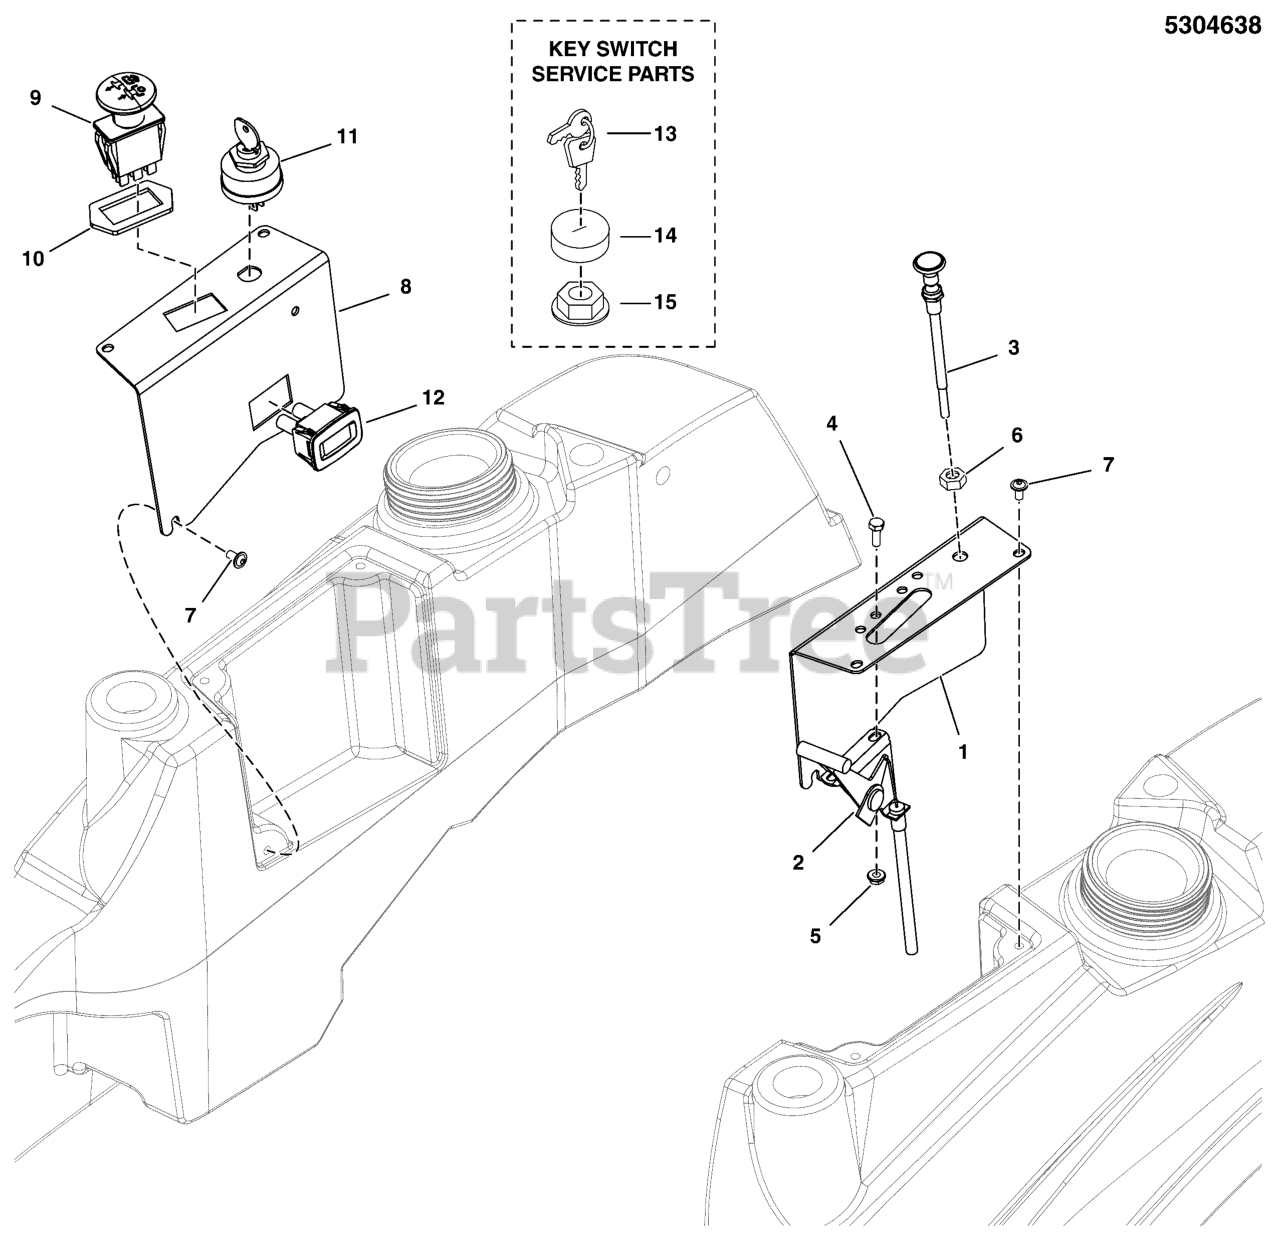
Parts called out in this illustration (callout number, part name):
1	PLATE, CONTROL PANEL, LH, F60Z - BLK
2	CABLE, THROTTLE CONTROL, 51"
3	CABLE, CHOKE CONTROL, 51" (Z)
4	HHCS, 1/4-20 X 0.625, GR5, ZINC/CLEAR
5	NUT, 1/4-20 Hex Nylock Flange
6	NUT, 3/8-24 Hex Jam
7	SCREW, ALLEN HEAD 1/4-20X.500 ZINC PHOS
8	CONTROL PANEL, RH, F60Z - BLK
9	SWITCH-PTO PUSH
10	RING, SWITCH RETAINER
11	SWITCH, IGNITION, 6 POST
12	HOUR METER, ASSEMBLE
13	KEY, IGNITION MOLDED SET
14	COVER, PLASTIC, SNAP ON
15	PLASTIC NUT
